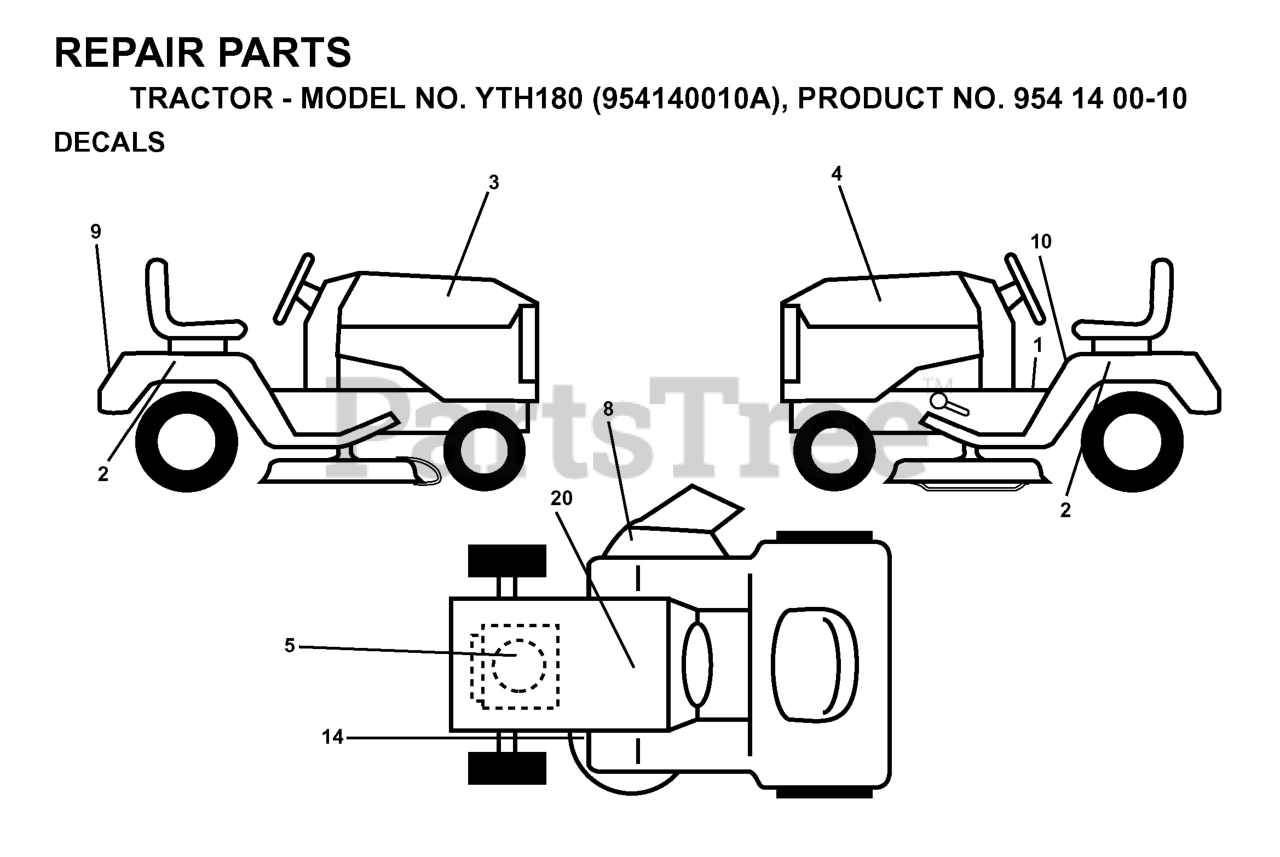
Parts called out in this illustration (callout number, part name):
3	DECAL L.H. YTH180
4	DECAL R.H. YTH180
8	DECAL WARNING (ENGLISH/FRENCH)
9	DECAL FENDER HUSQ
10	DECAL FENDER DANGER
20	DECAL, BATTERY DANGER
